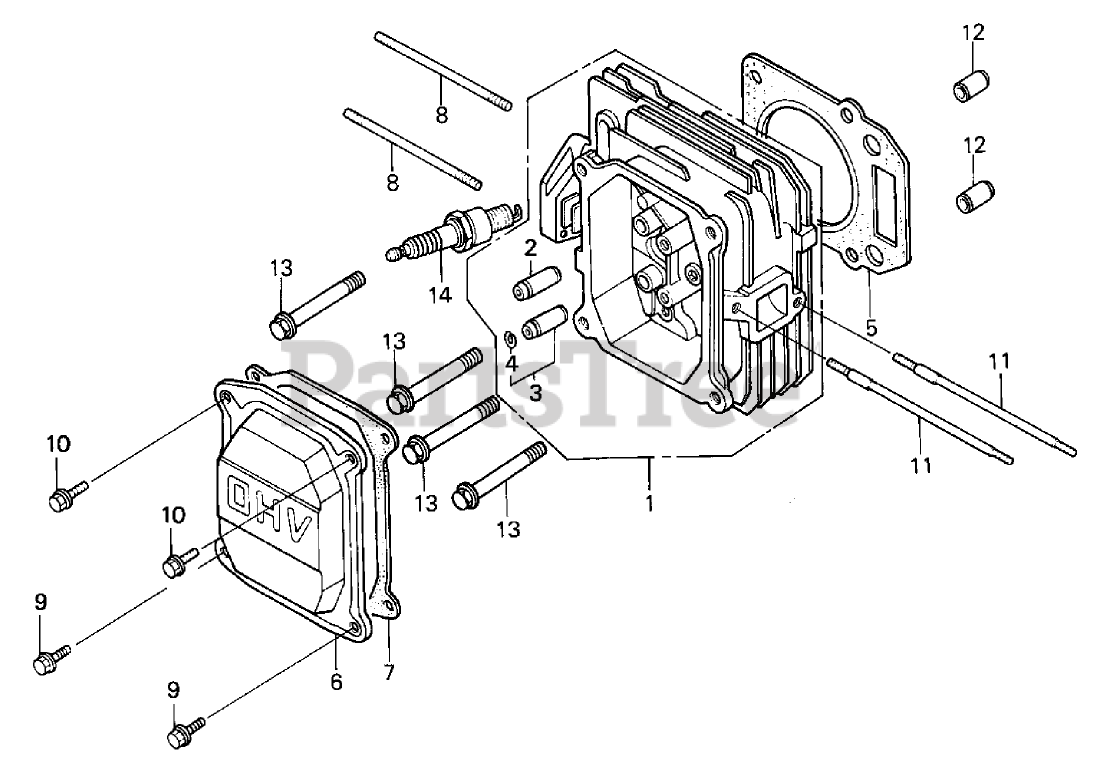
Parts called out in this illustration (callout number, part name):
1	Head-Cylinder
2	GUIDE-VALVE (O S)
3	GUIDE-VALVE, EXHAUST (O S)
4	CLIP-GUIDE, VALVE
5	GASKET-HEAD, CYLINDER
6	Cover-Head
7	Gasket-COVER, Cylinder Head
8	BOLT-STUD (6X85)
9	BOLT-FLANGE (6X12) (C T200)
10	BOLT-FLANGE (6X12) (C T200)
11	BOLT-STUD (6X109)
12	PIN-DOWEL (10X16)
13	BOLT-FLANGE (8X50)
14	SPARK PLUG (B P R4E S) (N G K)
